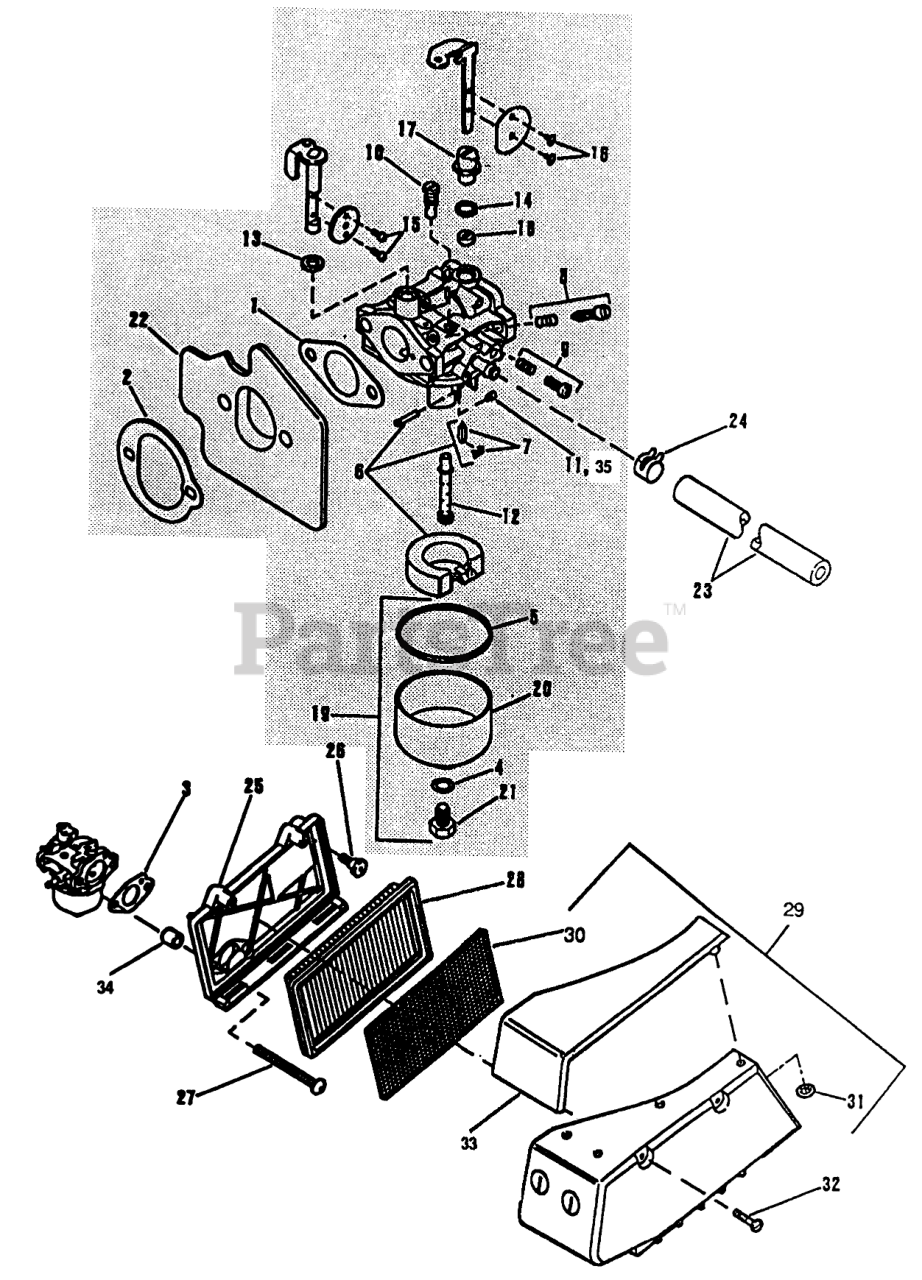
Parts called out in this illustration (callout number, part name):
1	GASKET SM
2	GASKET SM
3	GASKET-FIL SM
4	GASKET-BOWL RET S
5	GASKET-FUELBOWL S
6	FLOAT & NEEDLE S
7	NEEDLE & CLIP S
8	IDLE NEEDLE&SPRING
9	IDLE SPD.SCRW.KIT
10	PILOT JET
11	CARB JET
12	Nozzle
13	Thottle Shaft Seal
14	SEAL CHOKE SHAFT
15	SCREW THROT VALVE
16	SCREW CHOKE VALVE
17	PIVOT CHOKE SHFT
18	PIVOT CHOKE SHFT
19	BOWL KIT
20	Bowl-Fuel
21	SCREW,BOWL RET S
22	SPACER & NOZZ SM
22	SPACER -CARB. SM
23	GAS LINE SM
24	HOSE CLAMP SM
25	BASE-AIR FILT SM
26	BOLT SHOULDER SM
27	Screw
28	ELEMENT-AIR SM
29	AIR FILTER COVER
30	PREFILTER SM
31	NUT-PUSH
32	SCREW SM
33	COVER AIR BOX SM
34	SPACER SM
35	MAIN JET
